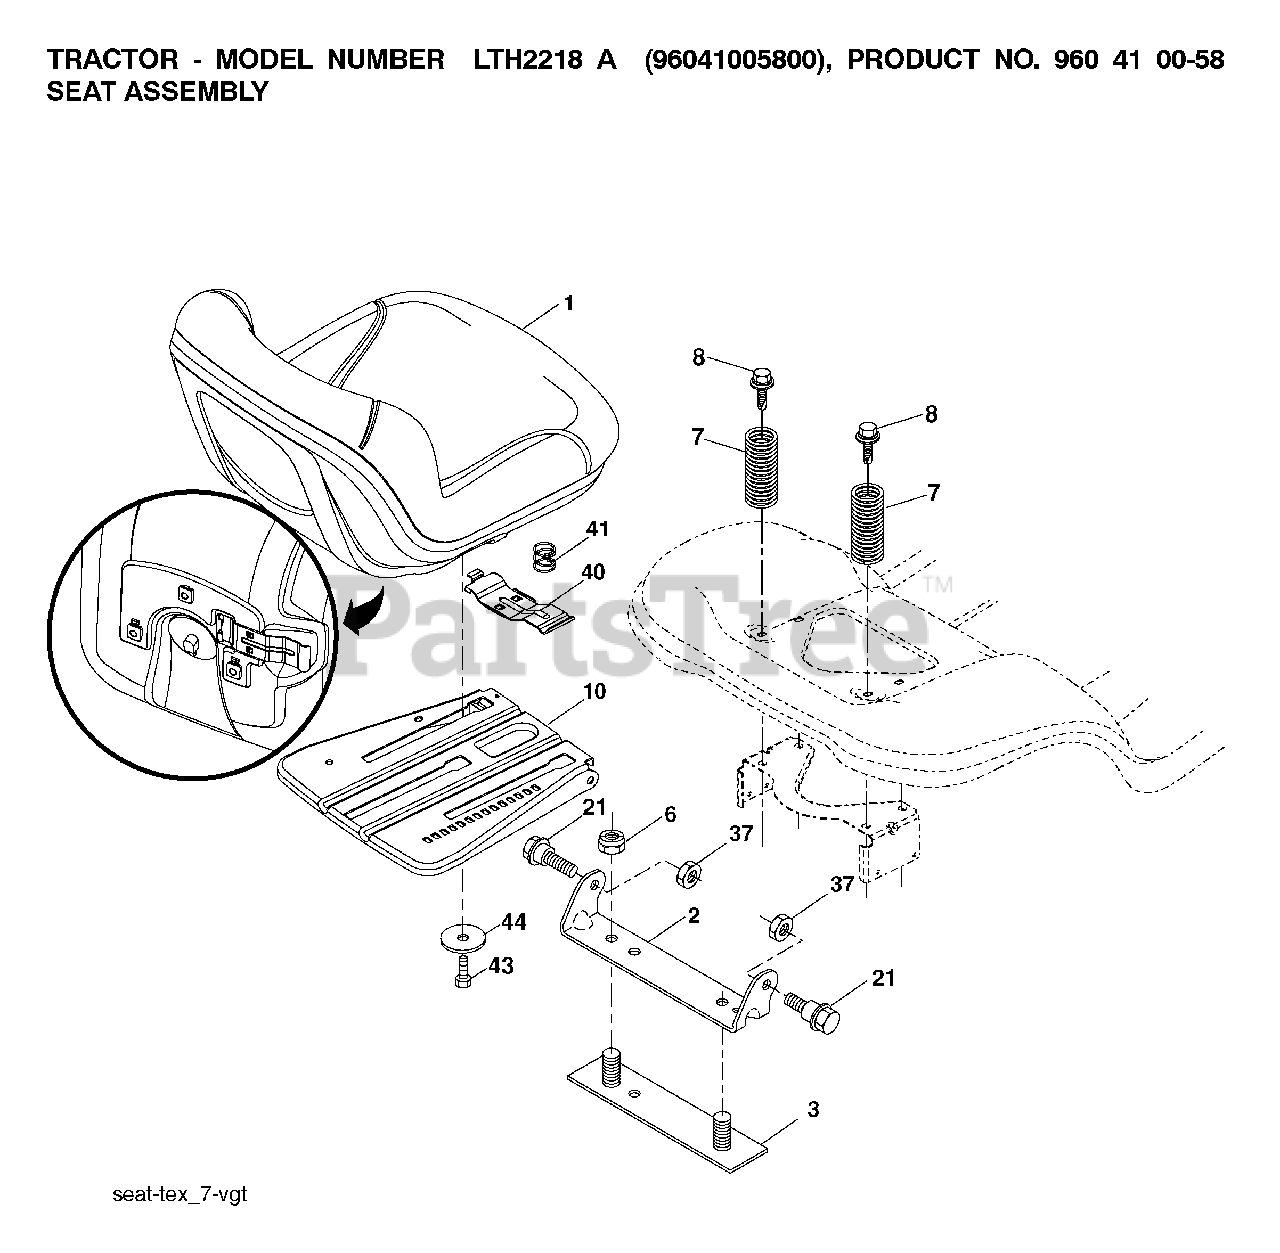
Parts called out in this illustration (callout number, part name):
1	SEAT.TG150.BLK.NLOGO.
2	BRKT.PIVOT.FENDER
6	NUT
7	SPRING COMPRESSION
8	BOLT, 5/16-18 X 1 3/4
10	PAN.ASM.SEAT.3PT
21	BOLT.SHOULDER.5/16-18
37	NUT.71038.31-18.HEX.NYLOCK
40	HANDLE.SLIDE.SEAT.TEX.BLACK
41	SPRING.LATCH.SEAT.TEX
44	WASHER 13/32 X 2-3/8 X 12GA
